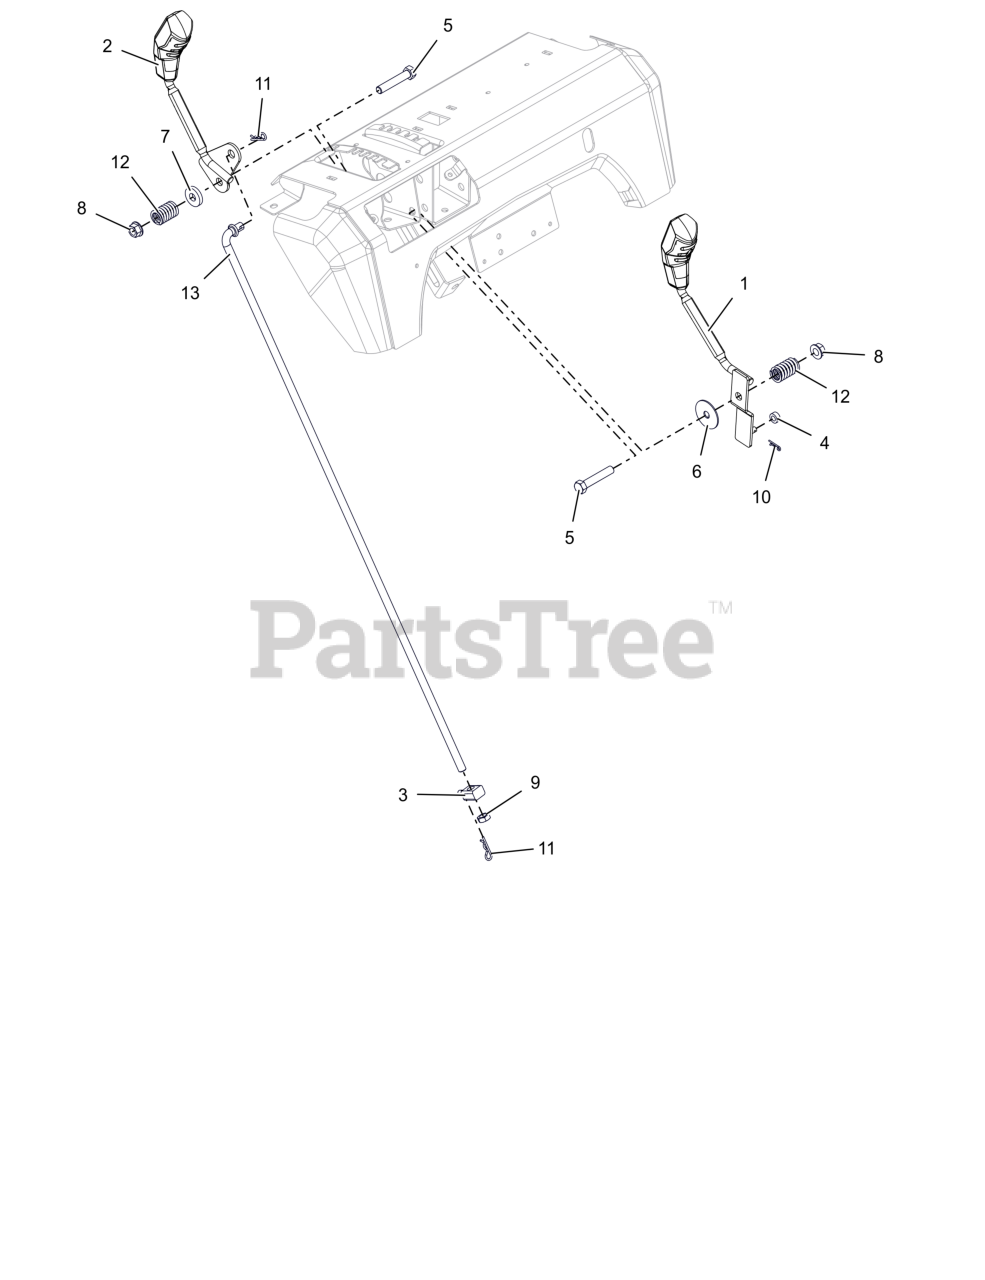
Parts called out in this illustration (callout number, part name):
1	ASM, LEVER W/KNOB-LG DASH DEFL
1	KNOB, CONTROL
2	ASM, LEVER W/KNOB-LG DASH SPEED
2	KNOB, CONTROL
3	PIVOT,SHIFT ROD .375-16(TRUNN)
4	BSHG-SLV .265X.500X.219
5	BLT,HEX .38-16X2.00 G5 ZCC
6	WSHR,FLT .380X1.50X.062 ZCC
7	WSHR, FLT .406X1.00X.188 ZCC
8	NUT-LK-TOP-FLG .38-16 ZC120
9	NUT-JAM .375-16 G2 ZCC
10	PIN, HAIR #178 .06X.77 ZCC
11	PIN, HAIR #213 .08X1.19 ZCC
12	SG-COMP .125X.781X1.250
13	ROD, SHIFT - LARGE DASH DELUXE
